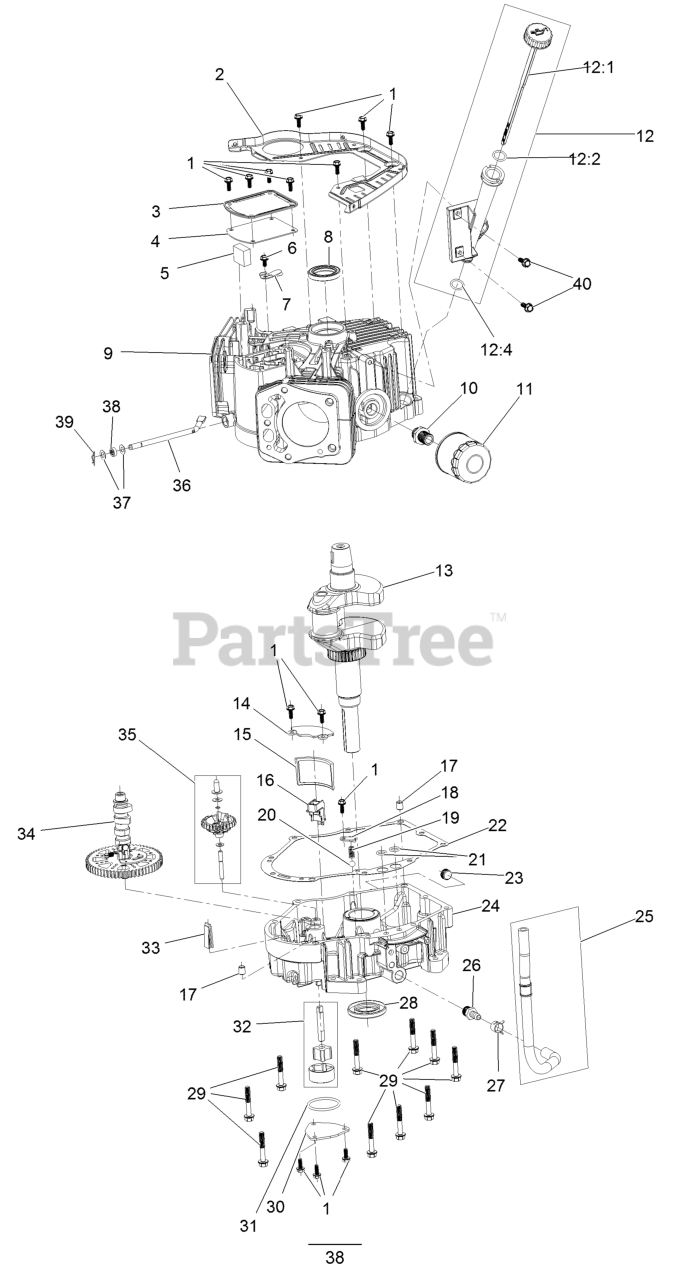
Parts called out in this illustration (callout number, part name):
1	SCREW-HHF
3	COVER-BREATHER
4	GASKET-BREATHER
5	FILTER-BREATHER
6	SCREW-HHF
7	VALVE-BREATHER
8	SEAL-OIL
9	CRANKCASE
12	OIL TUBE ASM
12:1	DIPSTICK
13	CRANKSHAFT
14	COVER-SCREEN, OIL
15	SCREEN-OIL
16	RETAINER-SCREEN
17	PIN-DOWEL
18	PLATE-RETAINER
20	VALVE-BALL
22	GASKET-COVER, CRANKCASE
23	PLUG-DRAIN
24	COVER-CRANKCASE
25	OIL DRAIN HOSE ASM
26	FITTING-HOSE
27	CLAMP-HOSE
29	SCREW-HHF
30	COVER-OIL PUMP
32	OIL PUMP ASM
33	DEFLECTOR-OIL, RUBBER
36	SHAFT-GOVERNOR
37	WASHER-PLAIN
38	SEAL-OIL
39	PIN-HAIR
40	SCREW-HHF
